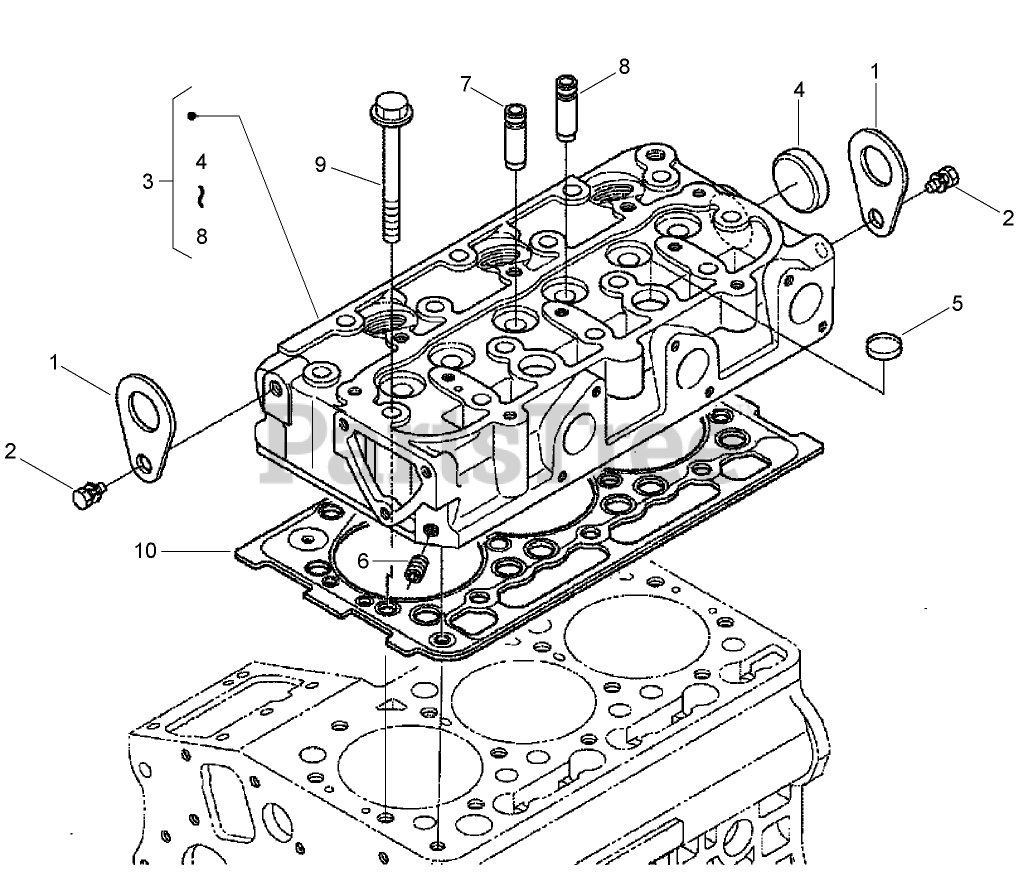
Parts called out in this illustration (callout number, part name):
1	HOOK-ENGINE
3	HEAD-CYLINDER
4	CAP-SEALING
5	CAP-SEALING
6	PLUG
7	GUIDE-VALVE, INLET
8	GUIDE-VALVE, EXHAUST
9	BOLT-HEAD, CYLINDER
10	OBS GASKET-HEAD, CYLINDER
